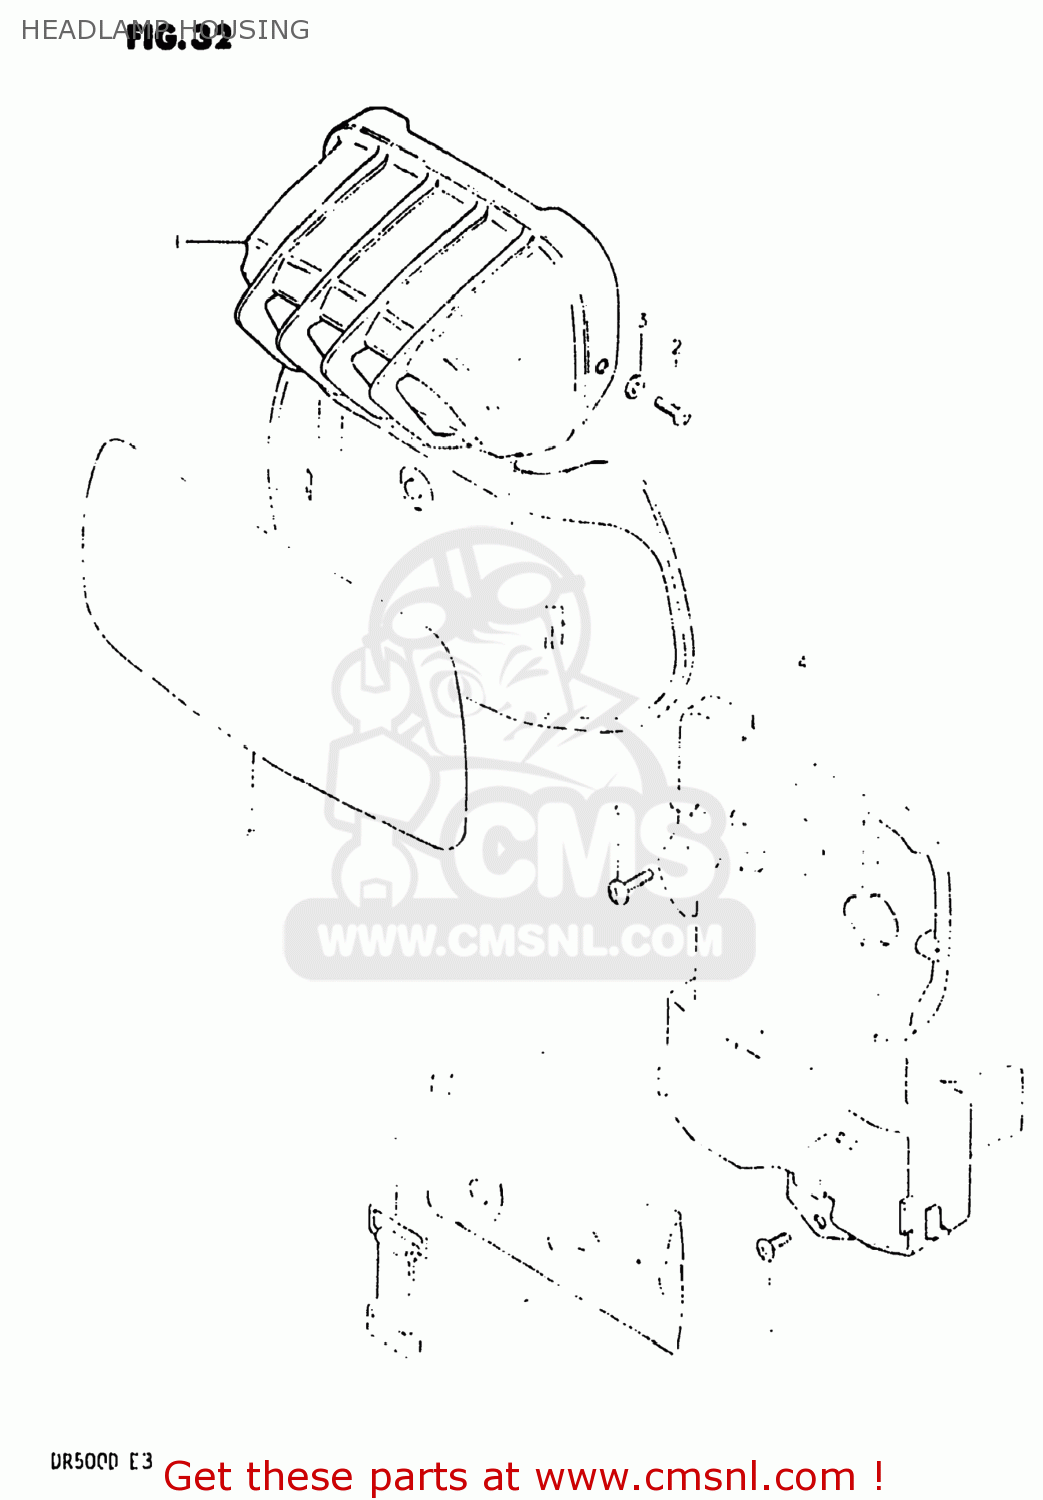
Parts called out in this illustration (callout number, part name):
1	HOUSING,HEADLAMP
2	TAPPING SCREW
3	WASHER
4	HOLDER,TOOL
5	BAND
6	SCREW
7	SCREW
8	EMBLEM,FRONT NUMBER PLATE
9	TOOL SET
